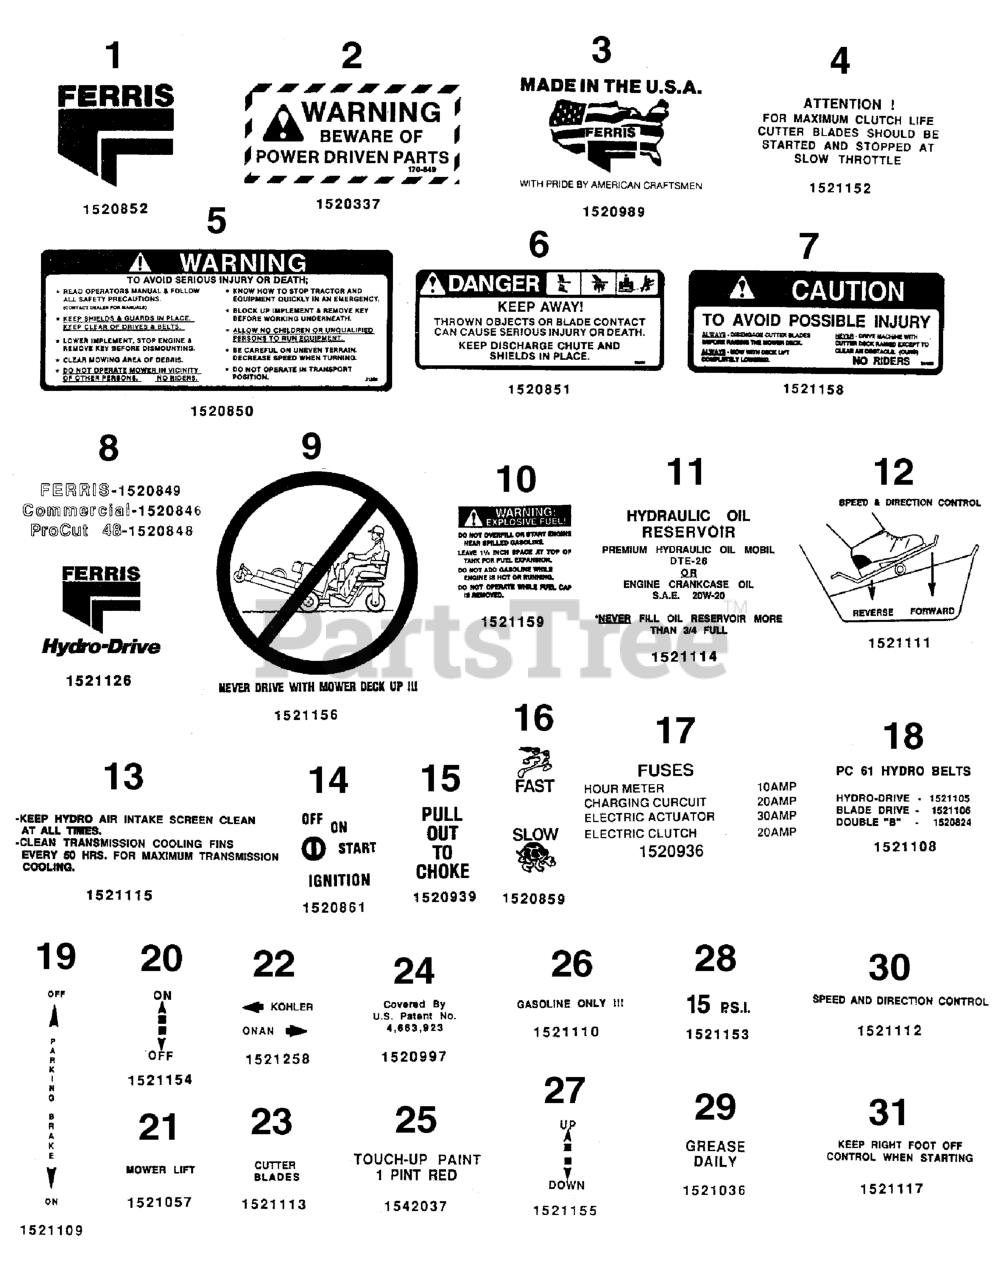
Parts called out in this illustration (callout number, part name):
1	DECAL, Ferris Logo, 10-3/4"
2	DECAL, Warning
3	DECAL, Made In The USA
4	DECAL, Attention Belt Life
5	DECAL, WARNING Operation
6	DECAL, DANGER DO NOT OPERATE W/O DEFLECT
8	DECAL, FERRIS TEXT & LOGO
8	DECAL, Commercial
8	DECAL, Word, PROCUT 48
8	DECAL, Hydro Drive
9	DECAL, Never Drive With Mower Deck Up
10	DECAL, EXPLOSIVE FUEL
11	DECAL, Reservior Hydraulic Oil
12	DECAL, Speed Control
13	DECAL, Hydro Screen
14	DECAL, Ignition
16	DECAL, Engine Speed
17	DECAL, Fuses
18	DECAL, Belt & Blade
19	DECAL, PARKING BRAKE-RIDER
20	DECAL, PTO Switch
21	DECAL, Mower Lift
22	DECAL, Kohler Onan
23	DECAL, PTO Switch
24	DECAL, Patent
25	DECAL, Touch-Up Paint
26	DECAL, Gasoline Only
27	DECAL, Up / Down
28	DECAL, 15 P.S.I.
29	DECAL, Grease Daily
31	DECAL, Right Foot Control
